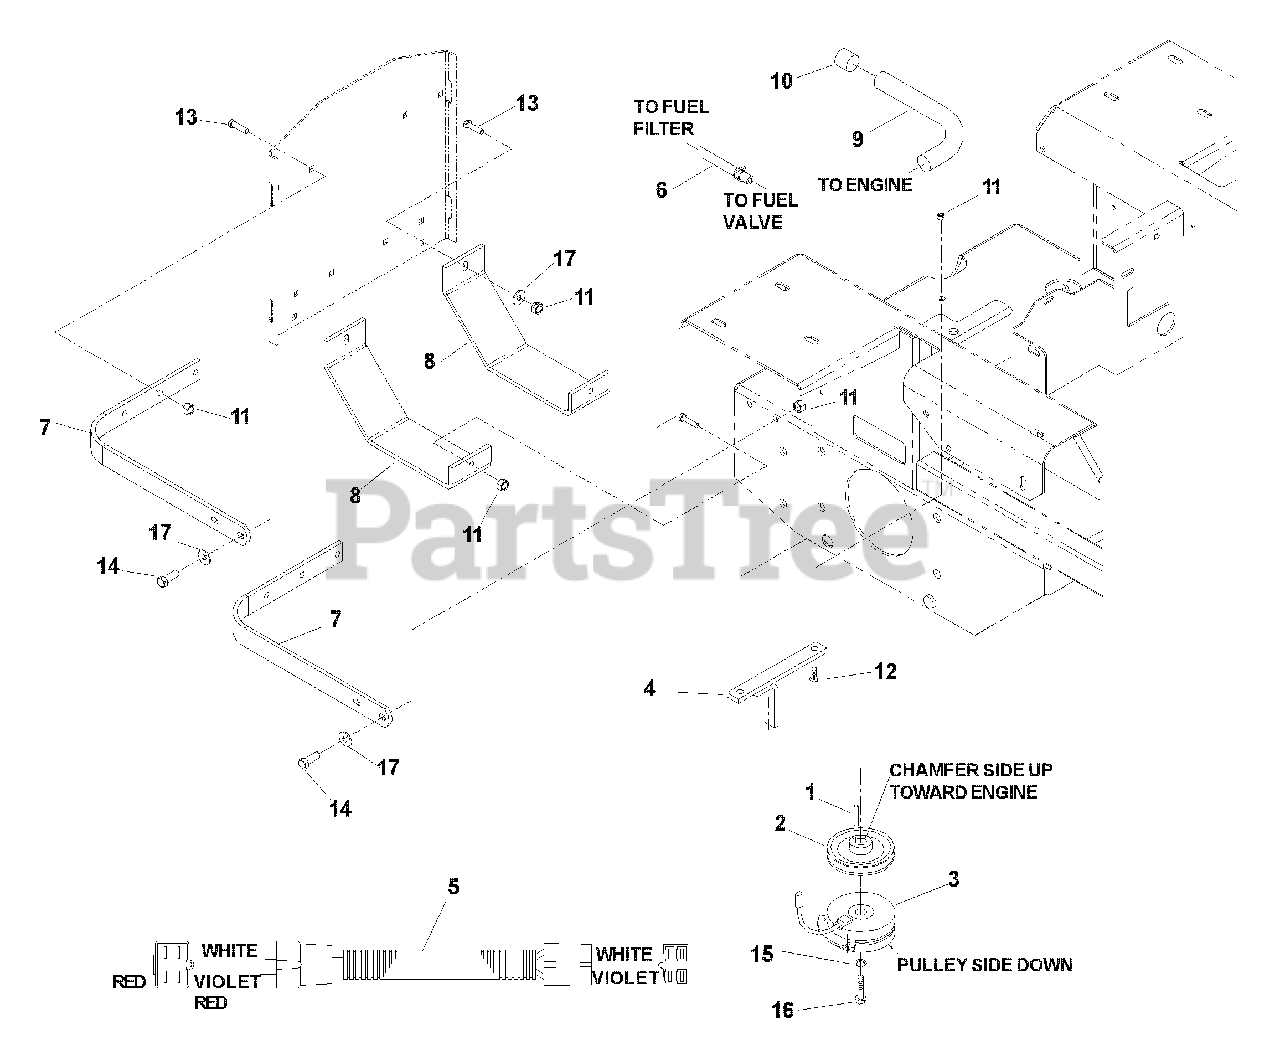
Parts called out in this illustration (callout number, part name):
1	KEY, 1/4 SQ X 1 1/4
4	CLUTCH TIE DOWN
6	FUEL HOSE, 16"
8	SKID PLATE
9	OIL DRAIN HOSE
10	OIL DRAIN CAP
11	NUT, 5/16C, NYLOC
12	HCS, 5/16C X 1 3/4
13	RHSSNB 5/16C X 1
14	HCS, 5/16C X 1
15	LOCKWASHER, 7/16
16	HCS, 7/16F X 2 1/2
17	WASHER, 5/16, FLAT
